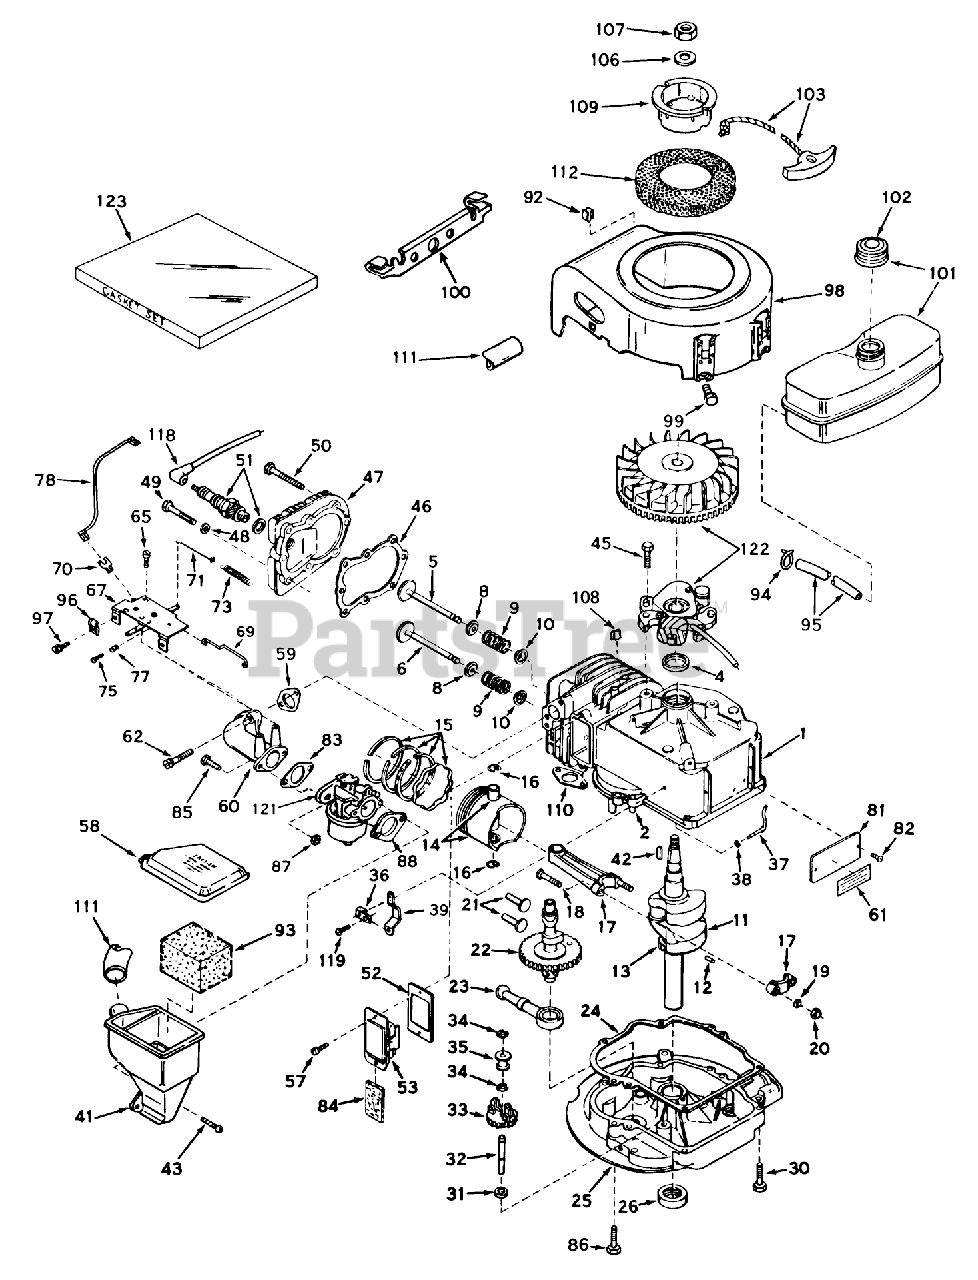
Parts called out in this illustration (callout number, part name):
1	Cylinder Assy. (Incl. Nos. 2, 4 103)
2	Pin-Dowel
4	OIL SEAL
5	Valve, Intake (Incl. Ref. #38, 39 40) (Std.)
5	Valve, Exhaust (1/32" Oversize) (Incl. Nos. 8, 9 10)
6	Valve, Exhaust (Standard) (Incl. Nos. 8, 9 10)
6	Valve, Exhaust (1/32" Oversize) (Incl. Nos. 8, 9 10)
8	Cap-Upper Valve Spring
9	Spring-Valve
10	Cap-Valve, Spring
11	Crankshaft Assy. (Incl. Ref. 12 13)(Model LAV35-40455H)
12	Pin, Groove
13	Gear, Crankshaft
14	Piston Pin Assy. (Standard) (Incl. 2 of No. 16)
14	Piston Pin Assy. (.010 Oversize) (Incl. 2 of No. 16)
14	Piston Pin Assy. (.020 Over size)(Incl. 2 of No. 16)
15	Ring Set, Piston (Std.)
15	Ring Set, Piston (.010 o.s.)
15	Ring Set, Piston (.020 o.s.)
16	Ring-Retaining, Piston Pin
17	Rod Assy., Connecting (Incl. Ref. #17)
18	Bolt, Connecting
19	Washer
20	LOCKNUT
21	Lifter-Valve
22	Camshaft (Compression Release
23	Oil Pump ASM
24	Gasket, Mounting
25	Flange Assy., Mounting (Incl. #26 32)
26	Seal Oil
30	Screw (1/4-20 x 1-1/4)
31	Washer-Flat
32	Shaft-Governor
33	Governor Gear ASM
34	Ring-Retaining
35	Spool-Governor
36	Clamp-Lever, Governor
37	Rod, Governor (Incl. No. 36)
38	Washer-Flat
39	Governor Lever
41	Body, Air Cleaner
42	Key Flywheel
43	Screw, Fil. Hd. Sems
45	Screw
46	Gasket-Cylinder Head
47	CYLINDER HEAD
48	Washer
49	Screw
50	Screw Hex Hd. Cap
51	Plug, Spark (J17LM or equiv.)
52	Gasket Breather
53	Breather Assembly (Incl. Nos. 52 84)
57	Screw
58	Cover, Air Cleaner
59	Gasket, Intake
60	Pipe, Intake
61	480B GIL SNWTHWR O/
62	Screw (1/4-20 x 1)
65	Screw (10-24 x 9/16)
67	51089 SUPP TO MANUA
69	Link Governor
70	Terminal
71	Link-Governor
73	Spring, Governor
75	Screw
77	Spring-Compression
78	Wire, Ground
81	IDENTIFICATION PLATE
82	Stud
83	Gasket
84	Element-Breather
86	Screw
87	Nut and Lock Washer (1/4-28)
88	Gasket-Air Cleaner
92	51004 GIL ROTARY TI
93	Element, Air Cleaner
94	Clamp-Line, Fuel
95	Line-Fuel (8.62)
96	Conduit
97	Screw (10-32 x 3/8)
98	Housing, Blower
99	Screw (1/4-20x19/32)
100	Bracket, Shroud
101	Tank, Fuel
102	Cap, Fuel Filler
103	Rope Assy., Starter
106	Washer
107	Hex Nut
108	Clip-Wire
109	Pulley Starter
110	Gasket Exhaust
111	Tube, Air Cleaner
112	Screen, Air
118	Cover-Spark Plug
119	Screw
121	Carburetor (Incl. No. 83)
122	Magneto
123	Gasket Set
